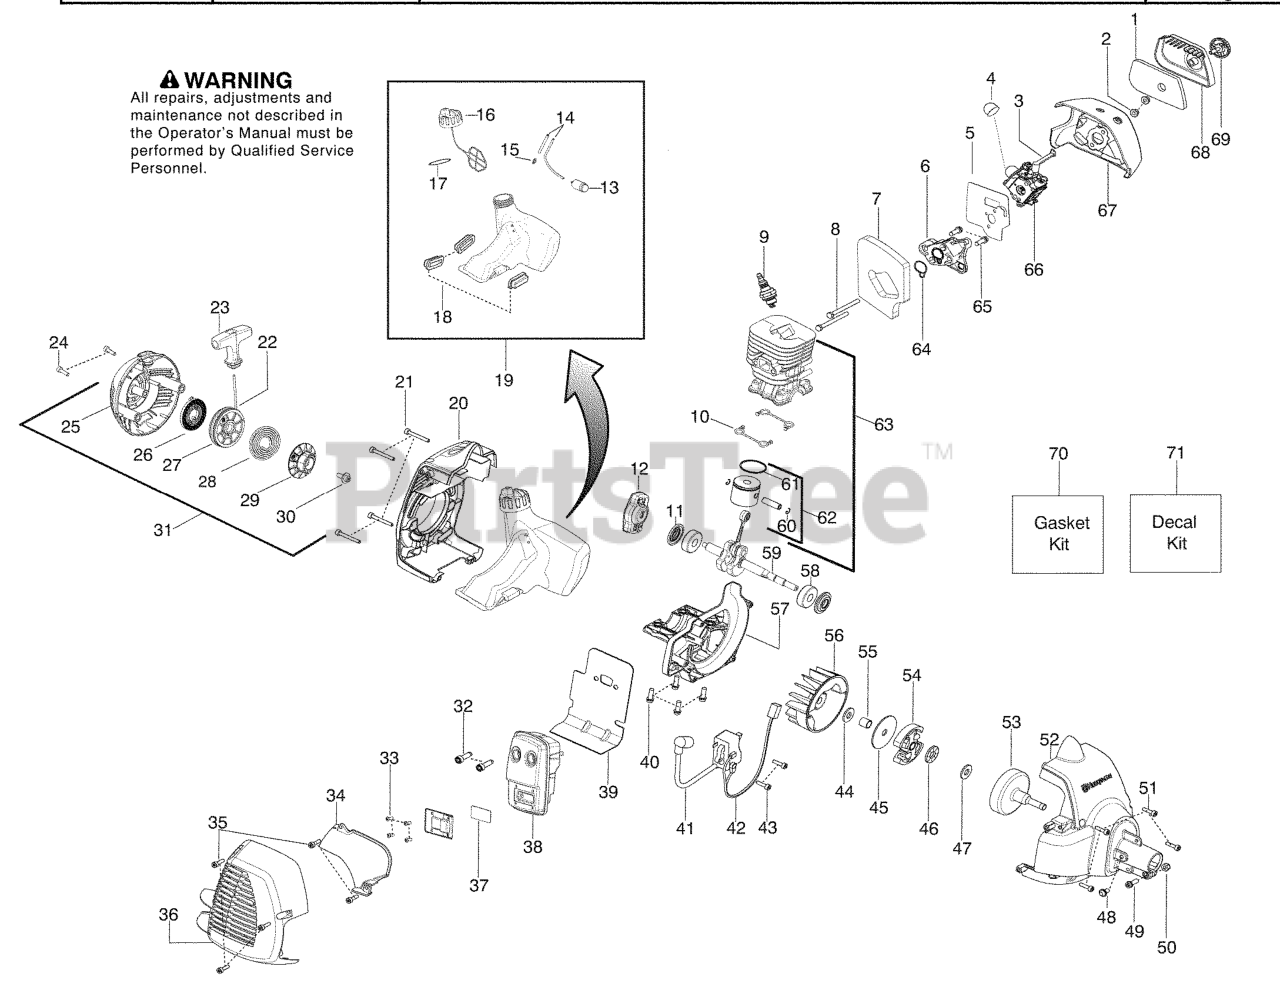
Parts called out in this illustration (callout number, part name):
2	Nut-Carb. Screw
3	Lever - Choke
4	Bulb-Purge
5	Kit-Carb. Gasket
6	Adaptor-Carb.
7	Foam-Gasket
9	Plug-Spark (RCJ-8Y)
10	Seal-Cylinder
11	Seal-Crankshaft
12	Assy-Starter Pawl
13	Assy-Fuel Filter
14	Kit-Fuel Line
15	Fitting-Fuel line
16	Assy-Cap w/ret.
17	O-ring - Fuel Cap
18	Isolator-Fuel Tank
19	Kit-Fuel Tank Assy.
20	Shroud-Rear
22	Kit-Rope
23	Handle-Starter
25	Hsg.-Starter w/eyelet
26	Kit-Spring
27	Kit-Starter Pulley
28	Spring - Driver
29	Pulley-Driver
31	Assy-Starter Hsg.
32	Bolt-Muffler
33	Screw
34	Shield-Heat
36	Guard-Muffler
37	Kit-Spark
38	Kit-Muffler
39	Gasket-Paper Met.
42	Assy-Leadwire
45	Washer-Clutch
46	Bearing - Thrust
47	Washer - Thrust
52	Assy-Fan Housing
53	Assy-Clutch Drum
54	Assy-Clutch
57	Crankcase-Cast
59	Assy-Crankshaft
60	Retainer-Piston Pin
61	Ring-Piston
62	Kit-Piston
63	Kit-Piston/Cyl.
64	Seal-adaptor
66	Kit-Carb.
67	Airbox
68	Cover-Air Box
70	Kit-Gasket
71	Kit-Decal
